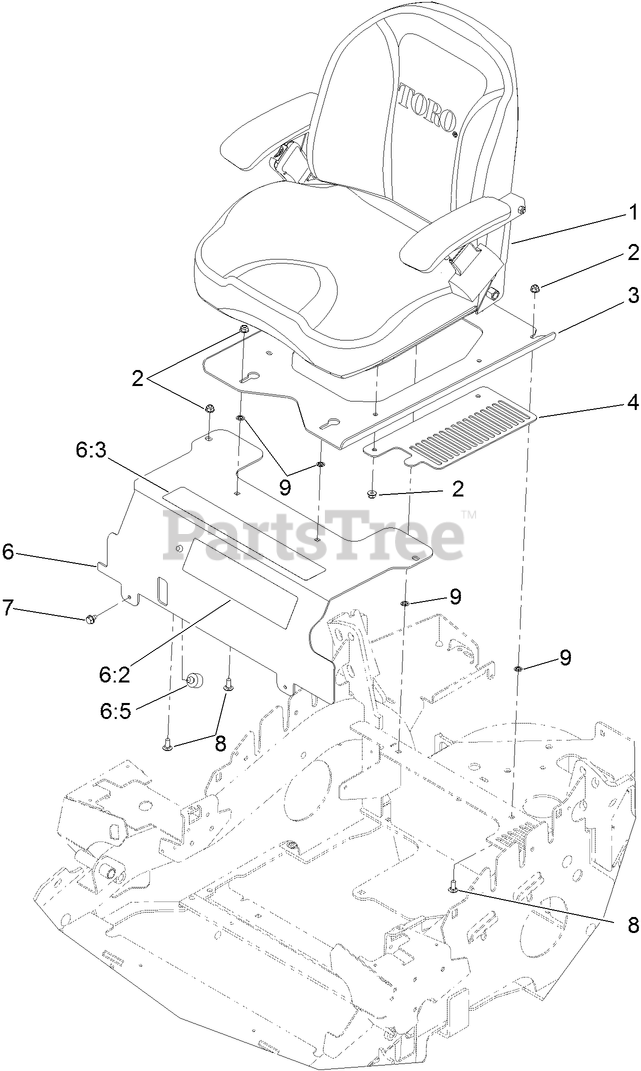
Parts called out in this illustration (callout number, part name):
2	NUT-HF, NI
3	PLATE-MOUNT, SEAT
4	PLATE-COVER, FAN
6	SEAT MOUNT PANEL ASM
6:3	DECAL-CONSOLE
6:5	BUMPER-GROMMET
7	SCREW
8	SCREW-CARR
9	NUT-PUSH
